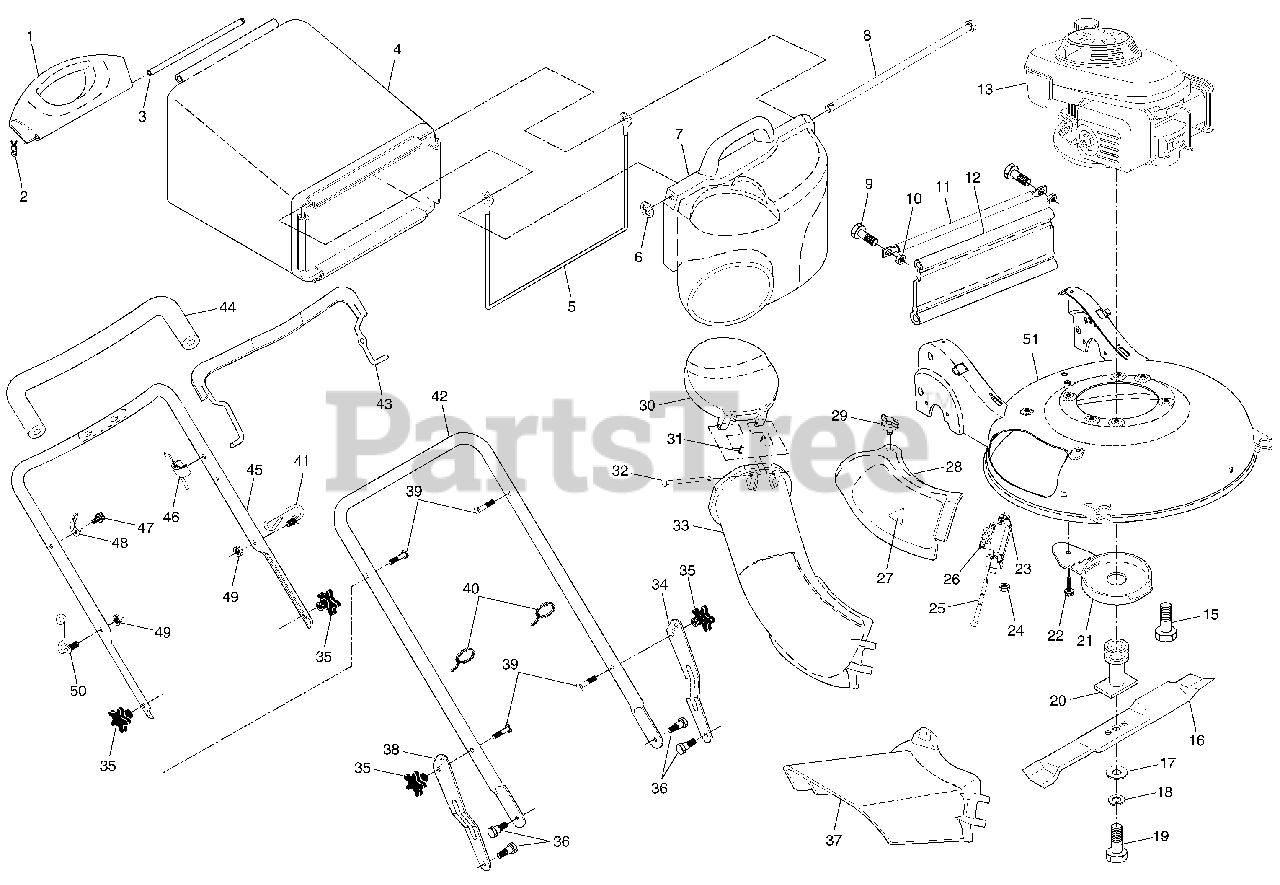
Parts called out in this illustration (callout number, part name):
1	Handle, Grassbag, Rear
2	Hairpin Cotter
3	Rod, Rear Handle, Grassbag
4	Grassbag
5	Frame, Grassbag
7	Door, Grassbag
8	Rod, Pivot
10	Nut, Hex, Nylock 1/4-20
11	Tube, Rear Skirt
12	Skirt, Rear
15	Bolt, Engine Mounting
16	Blade, 21"
17	Washer, Hardened
18	Washer, Lock
19	Screw, Hex Head, Grade 8
20	Adapter, Blade
21	Debris Shield
22	Screw, Hex Head, Serrated
23	Mounting Bracket, Mulcher Door
24	Nut, Hex
25	Rod, Hinge
26	Spring, Mulcher Door
27	Decal, Danger
28	Mulcher Door
30	Door, Discharge Chute
31	Spring, Door, Discharge Chute
32	Rod, Door, Discharge Chute
33	Discharge Chute, Plastic
34	Adjustment Bracket, Lower Handle, LH
35	Knob, Star
36	Bolt, Shoulder
37	Deflector, Discharge
38	Adjustment Bracket, Lower Handle, RH
39	Bolt, Handle
40	Wire Tie
41	Bracket, Anti-Fold
42	Handle Assembly, Lower
43	Bail, Control
44	Grip, Foam
45	Handle Assembly, Upper
46	Cable, Engine Zone Control
48	Bracket, Upstop
50	Rope Guide
51	Kit, Housing
